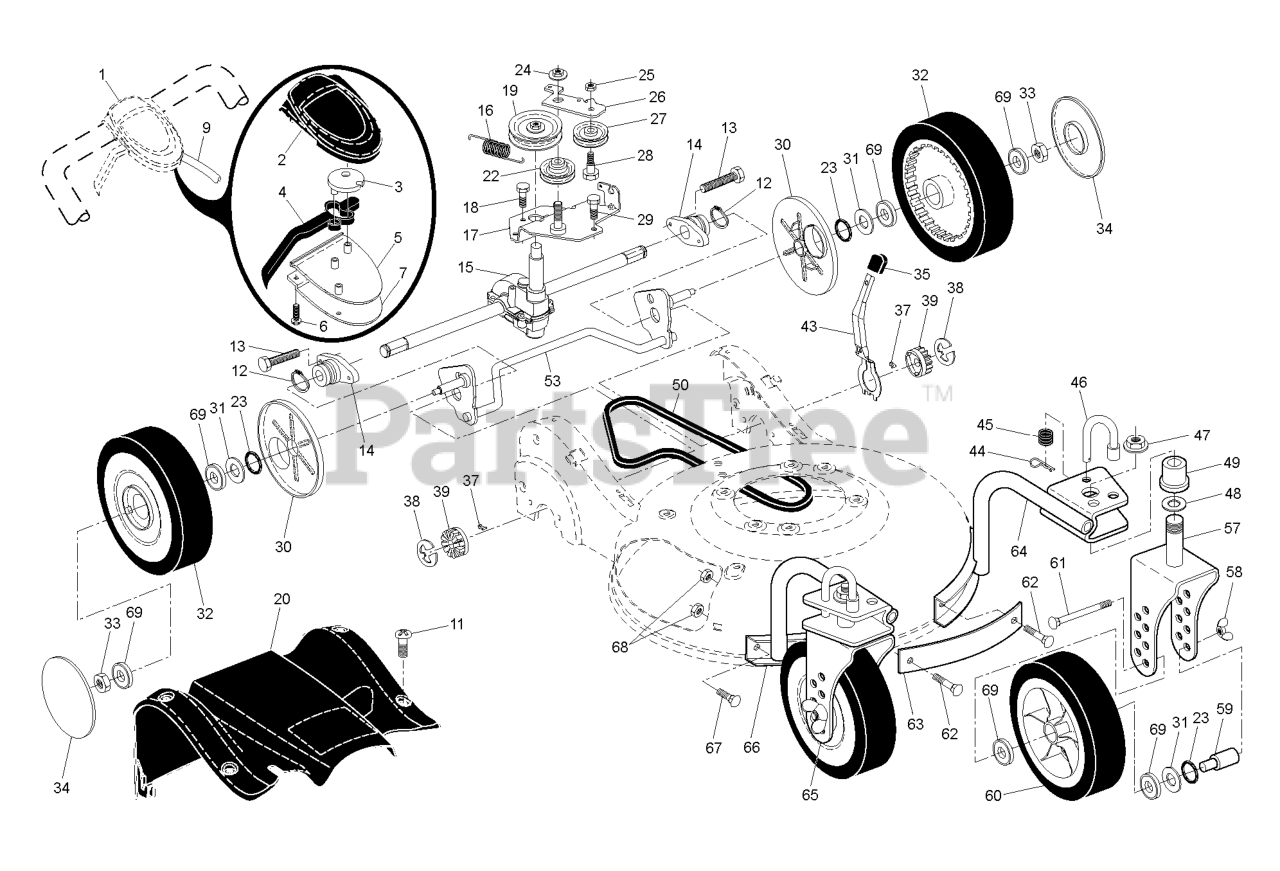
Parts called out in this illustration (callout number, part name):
1	Drive Control Assembly, Complete
2	COVER TOP AUTO WALK CONTROL
3	PULLEY.CAM.DRIVE.CONTROL.HV
4	LEVER.BLACK
5	COVER BOTTOM AUTO WLK CONTROL
6	SCREW, PHILLIPS HEAD 10 X 5/8
7	BRACKET.DRIVE.CONTROL.MOUNT.BL
9	ASM.CABLE.
10	COVER.DRIVE.REAR.21.HV.GRAY
12	RETAINING RING (2 2)(3 2)
13	HINGE SCREW
14	BEARING / AXLE SUPPORT
15	TRANSMISSION.21.HV.RWGD.AW/EZ
17	BRACKET, GEAR CASE / DRIVE
19	RP PULLEY.DRIVE.EZ
22	PULLEY.IDLER.V-BELT
23	O-RING
24	NUT.HEX.FLANGE.3/8-16.LOCKNUT
25	NUT.CENTERLOCK.5/16-
26	ARM.IDLER.BZP
27	IDLER PULLEY
28	SHOULDER BOLT
29	SCREW 14-20 X 5/8
30	DUST COVER, WHEEL
31	WASHER.FLAT.1/2
32	WHEEL.9X2.25.LP.TIGER.BLACK
33	NUT.HEX.FLANGE.3/8-16.LO(3 2)
34	HUBCAP.WHEEL.5.SPOKE.SILVER
35	KNOB.SELECTOR.SPRING.BLACK(3 2
37	PAWL, DRIVE
38	E-RING 7/16 RE
39	PINION.14.TEETH.FGD
43	LEVER, SELECTOR, HEIGHT, REAR
44	SPRING RETAINER
48	WASHER.FLAT.1/2
50	BELT, DRIVE
53	SHAFT.ASM.REAR.TORQUE.HV.BZP
55	Decal, Drive Control
57	BRACKET.WHEEL.ASM.LT.CASTER.OR
58	NUT.WING.5/16-18.YELLOW
60	WHEEL.9X2.25.LP.TIGER.SILVER
61	CARRIAGE BOLT
63	STRAP.FRONT.CASTER.ORANGE
64	SUPPORT.TUBE.ASM.LT
65	BRACKET.WHEEL.ASM.RIGHT.ORANGE
66	SUPPORT.TUBE.ASM.RT
68	NUT
69	BEARING.8".WHEEL
